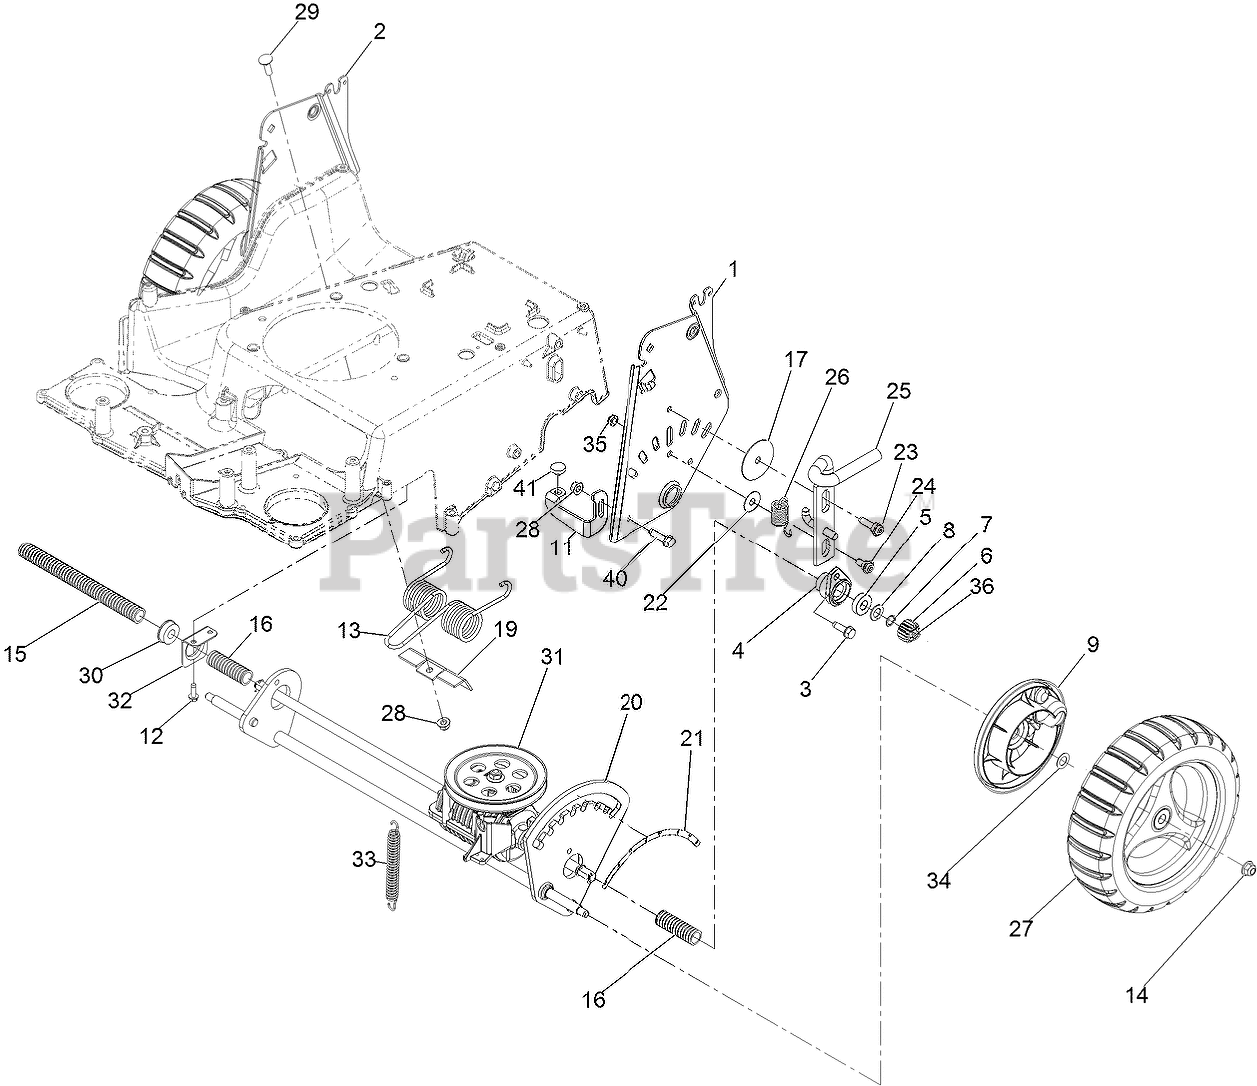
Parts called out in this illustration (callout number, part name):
1	LH HOC PLATE ASM
2	RH HOC PLATE ASM
3	SCREW-THD ROLL, HWH
4	RETAINER-BEARING
5	BEARING-BALL
6	GEAR-PINION, 15T
7	RING-RETAINING
8	WASHER-THRUST
9	COVER,GEAR
11	BRACKET-STOP, ADJUSTABLE
12	SCREW-HWHTF
13	SPRING-TORSION
14	NUT-HF, NI
15	CONDUIT-CONVOLUTED
16	CONDUIT-CONVOLUTED
17	WASHER-PLAIN
19	BRACKET
20	AXLE-REAR
21	DECAL-HOC, REAR
23	SCREW-SHOULDER, BHTF
24	BOLT-SHOULDER
25	LOCK-HEIGHT, ADJ
26	SPRING-EXTENSION
27	WHEEL ASM, 10.5 W/GEAR
28	NUT-HF, NI
29	BOLT-CARR
30	BEARING-BALL
31	TRANSMISSION KIT
32	MOUNT-BEARING
33	SPRING-EXTENSION
34	WASHER-PLAIN
35	NUT-LOCK, NI
36	PIN-SNAP
40	SCREW-HWHTF
